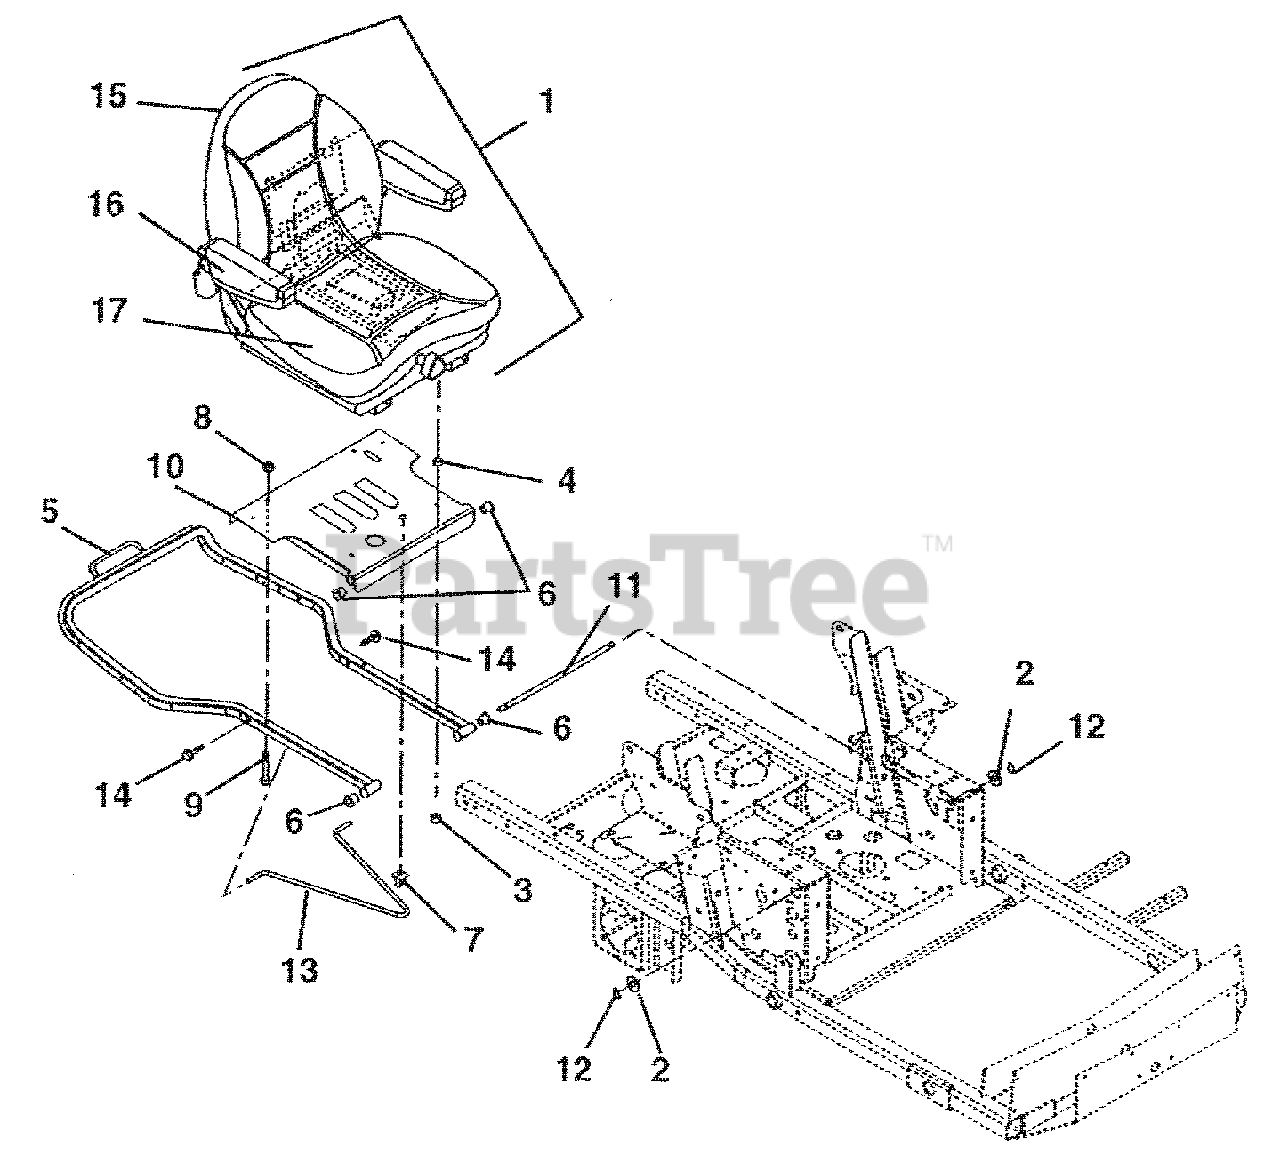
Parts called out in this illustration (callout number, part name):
1	Seat, Suspension
2	Washer, Flat Steel .531 x 1.06 x .095
3	Nut, Locking Top Flange .31-18
4	Bushing, Sleeve .377 x .624 x .235
5	Weldment, Hood Frame
6	Bushing-Flange .515 x .750 x .745 x 1.00
8	Nut, Locking Top Flange .38-16
9	Bolt, Rib Neck .38-16 x 1.50
10	Weldment, Seat Pivot Plate
11	Rod, Seat Frame Pivot
12	Ring, Retaining External .500 x .050
13	Rod, Prop
14	Screw, Tapping .25-20 x .50 Hex Washer Head
15	Kit, Back Cushion
16	Kit, Armrest
17	Kit, Seat Cushion
